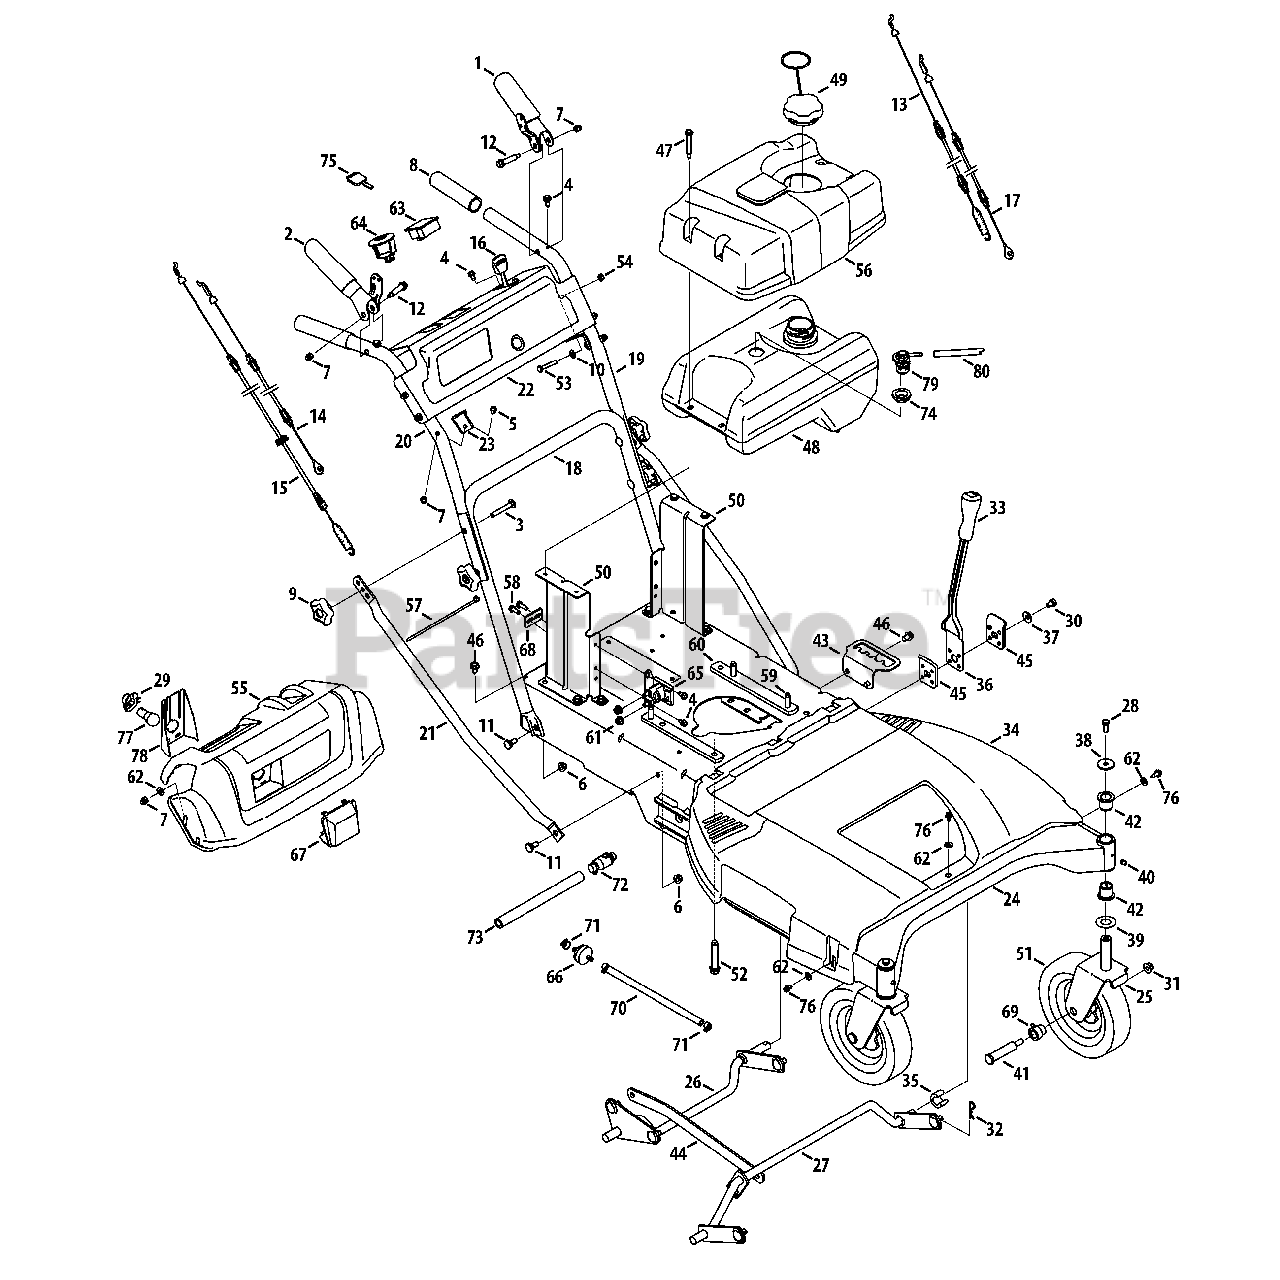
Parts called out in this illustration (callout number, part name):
1	Lever Assembly - LH
2	Lever Assembly - RH
3	Screw, Carriage, 5/16-18 x 2.25
4	Screw, 1/4-20 x 0.500
5	Screw, Cap, 1/4-20 x 1.50
6	Nut, Flange Lock, 5/16-18
7	Nut, Lock Cap, 1/4-20
8	Grip, 1.0 ID x 5.0 Lg
9	Star Knob, 5/16-18
10	Washer, Bell, .265 x .75 x .062
11	Screw, Shoulder, .435 x .178-5/16
12	Screw, Shoulder, .375 x 1.355, 1/4-20
13	Cable, Clutch Wheel
14	Cable, Brake, Transmission - RH
15	Cable, Clutch Deck
16	Cable, Throttle/Choke, 38 x 1.1
17	Cable, Brake, Transmission - LH
18	Lower Handle
19	Upper Handle - LH
20	Upper Handle - RH
21	Brace Tube
22	Handle Panel
23	Cable Mount Bracket - RH
23	Cable Mount Bracket - LH
24	Frame Assembly
25	Caster Wheel Bracket Assembly
26	Deck Lift Assembly, RR
27	Deck Lift Assembly, Front
28	Screw, HH Cap, 5/16-24 x .750
29	Lamp Socket
30	Screw, HH Cap, 5/16-18 x .50
31	Nut, Flange Lock, 3/8-16
32	Click Pin, .092 x 1.64
33	Handle Grip
34	Belt Cover
35	Snap Spacer, .63 ID x .75 LG
36	Deck Height Lever
37	Washer, Bell, .340 x .872 x .060
38	Washer, Flat, .330 x 1.25 x .120
39	Washer, Flat, .760 ID x 1.50 OD
40	Lube Fitting, 3/16
41	Bolt, Shoulder, .625 x 2.515 x 3/8-16
42	Flange Bearing, .760 x .941 x 1.0
43	Height Adjustment Bracket
44	Link Pivot Bracket
45	Lever Pivot Bracket
46	Screw, TT, 5/16-18 x .625
47	Screw, Shoulder, .32 x 1.8 x 1/4-20
48	Fuel Tank, 2 Gal.
49	Fuel Cap
50	Fuel Tank Mounting Bracket
51	Wheel, 8 x 1.75
52	Screw, TT, 3/8-16 x 2.25
53	Screw, HH Cap, 1/4-20 x 1.75
54	Nut, Hex, 1/4-20
55	Handle Panel
56	Tank Cover
57	Cable Tie
58	Screw, TT, 1/4-20 x .75
59	Screw, TT, 3/8-16 x 1.5
60	Engine Mounting Plate
61	Nut, Flange Lock, 1/4-20
62	Washer, Flat, .25 x .63 x .0515
63	Hour Indicator Meter
64	Key Switch
65	Solenoid, 12V
66	Fuel Filter
68	Shift Adjust Plate
69	Flange Bearing w/ Fitting
70	Fuel Hose
71	Hose Clamp
72	Oil Drain
73	Oil Drain Hose
74	Rubber Gromet
75	Key, Ignition, Black
76	Screw, 1/4-20 x 1.75
78	Label Reflector
79	Rollover Valve
80	Vent Hose
